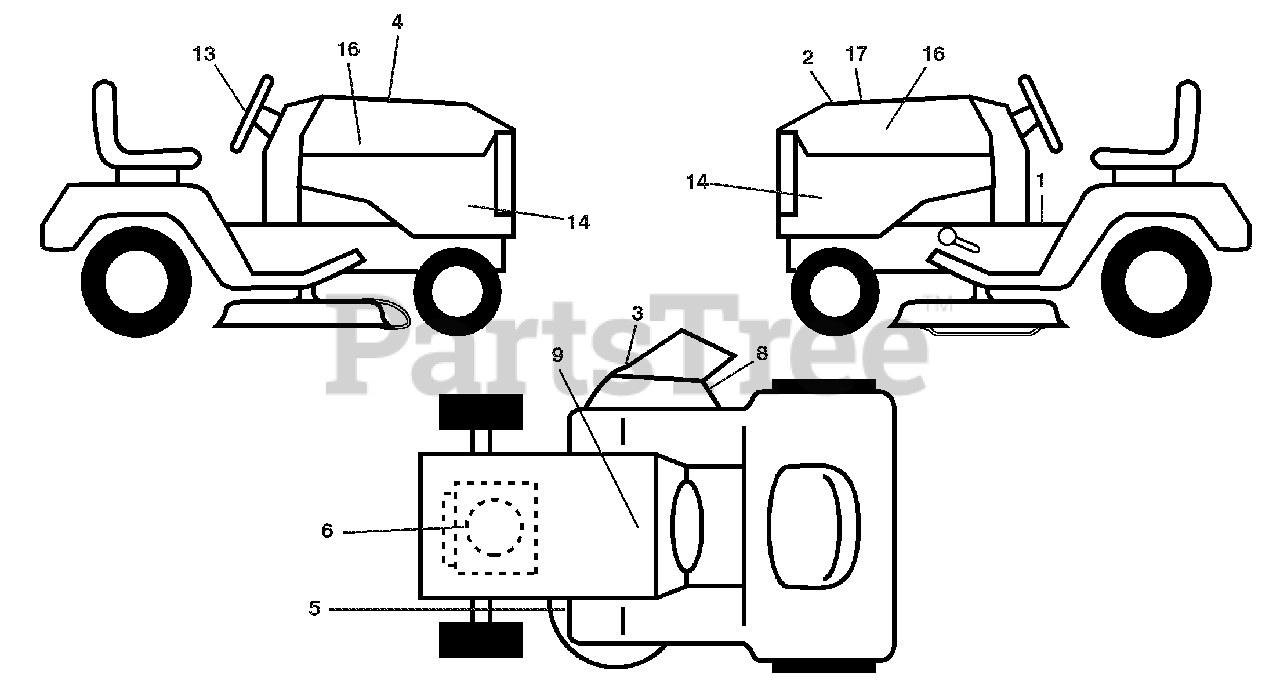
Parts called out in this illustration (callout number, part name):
1	Decal, Operator's
2	Decal, Hood Insert
3	Decal, Warning
4	Decal, Hood Cust Resp
5	Decal, Caution
6	Decal, Eng. HP
8	Decal, Mower Sch.
9	Decal, Battery Dnge/Poi
13	Decal, Steering Whl
14	Decal, Panel Side
16	Decal, Hood Logo
17	Decal, Replacement
18	Decal, Bypass
19	Pad, Footrest, LH
20	Pad, Footrest, RH
